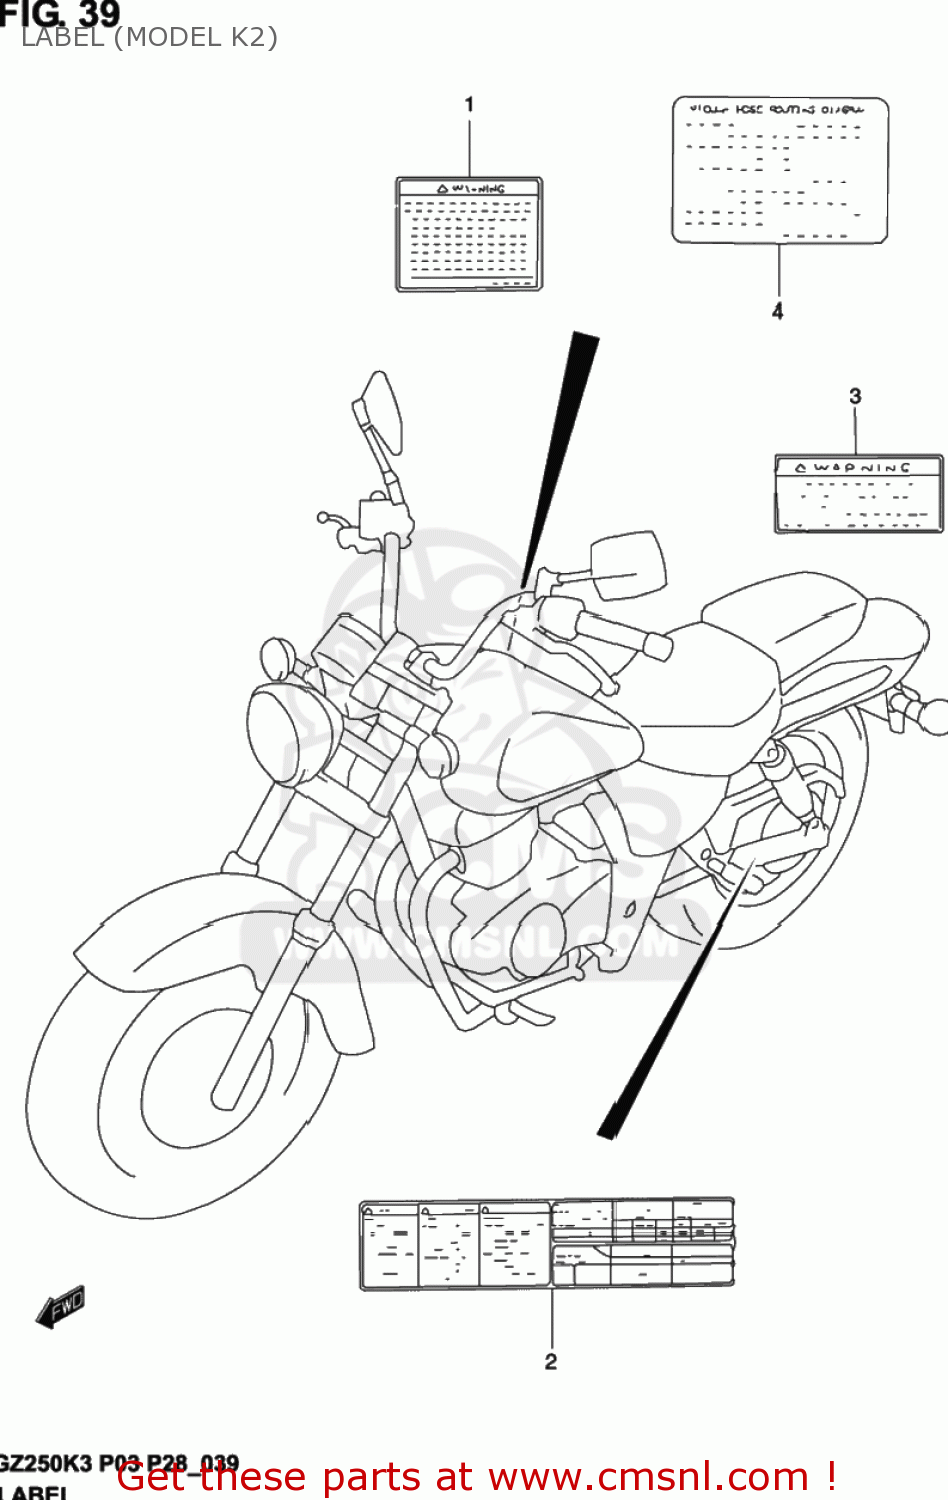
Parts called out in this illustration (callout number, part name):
1	LABEL,GENERAL WARNING
2	LABEL, TIRE INFORMATION
3	LABEL,MANUAL NOTICE
4	LABEL,VACUUM HOSE ROUTING
5	MANUAL, OWNER'S
